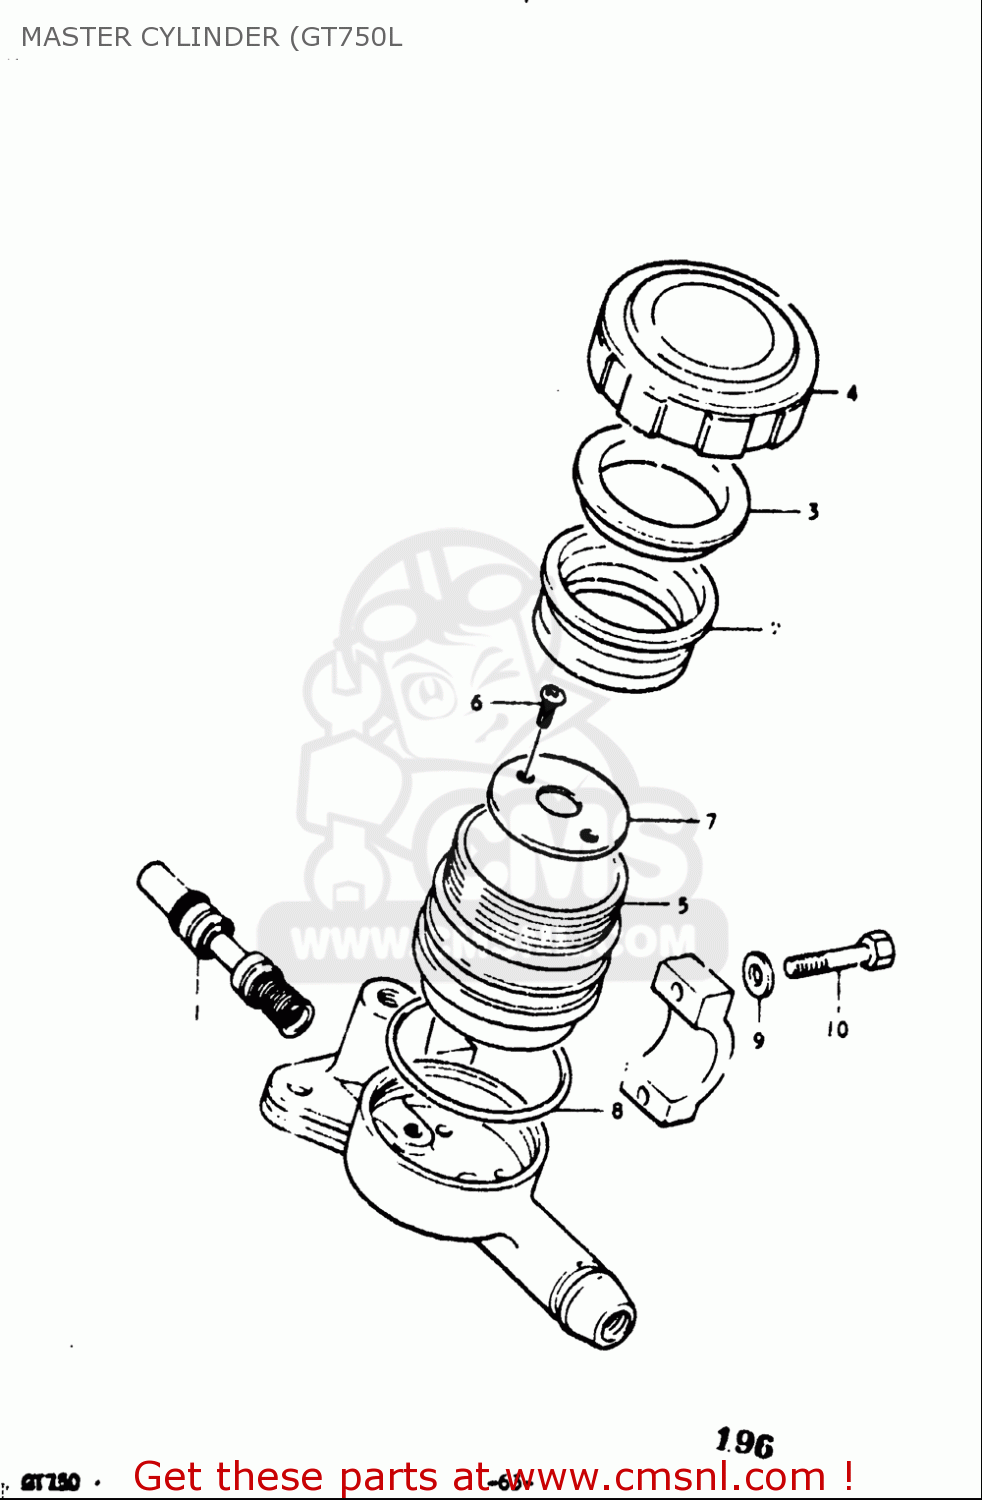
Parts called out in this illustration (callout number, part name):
1	PISTON & CUP SET
2	DIAPHRAGM
3	PLATE,DIAPHRAGM
4	CAP
5	RESERVOIR
6	SCREW
8	O RING
9	WASHER
10	BOLT
